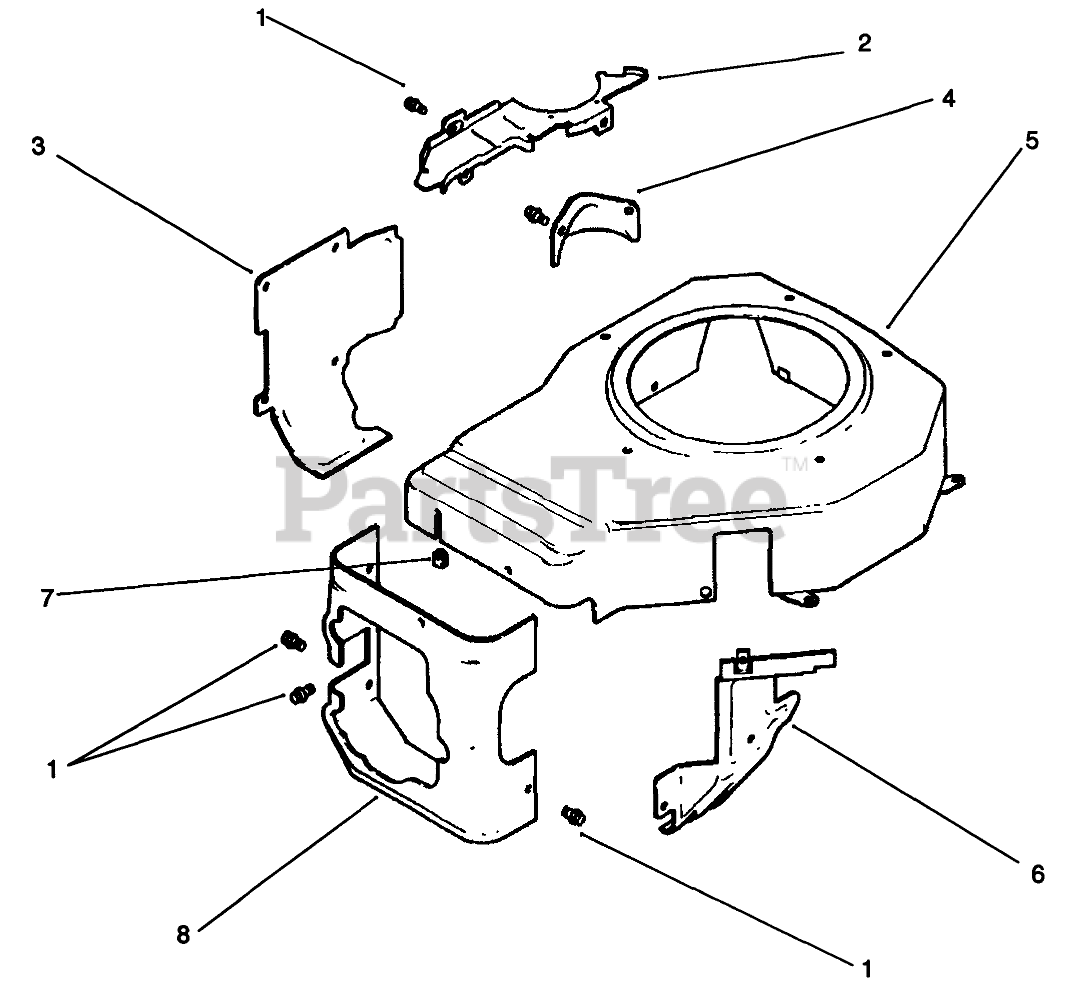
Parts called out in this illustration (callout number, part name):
2	Plate Blower
3	Babe-Cylinder Barrel
4	Cover-Starter
5	Cover-Housing
6	Bade-Carburetor
7	Grommet
8	Baffle-Cylinder Head
